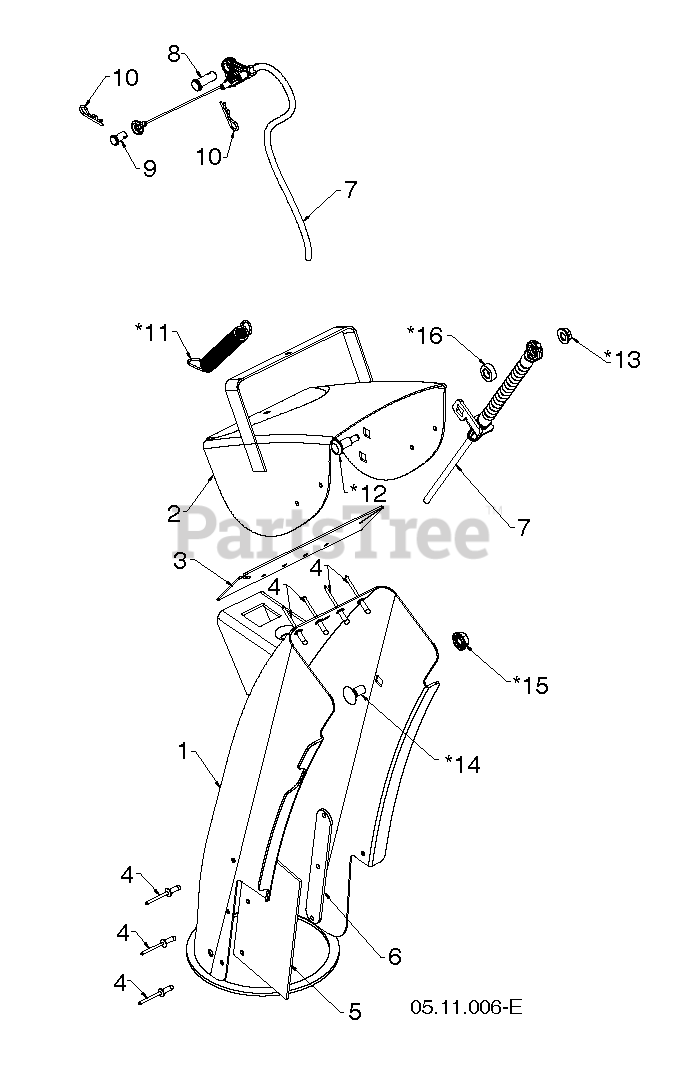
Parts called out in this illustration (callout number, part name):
1	DEFLECTOR, ASSY.
7	Deflector Chute Control Cable
8	Clevis Pin, 5/16 X .875
9	Clevis Pin, .25 X .31
11	SPRING.DEFLECTOR.REM.CHUTE
12	Shoulder Carriage Bolt
13	Flange Hex Lock Nut, 1/4-20 Large
14	Carriage Bolt, 5/16-18 X 5/8 Black
15	LOCKNUT-FLANGE 5/16-18
16	WASHER.NYLON.326 X.625 X.205
